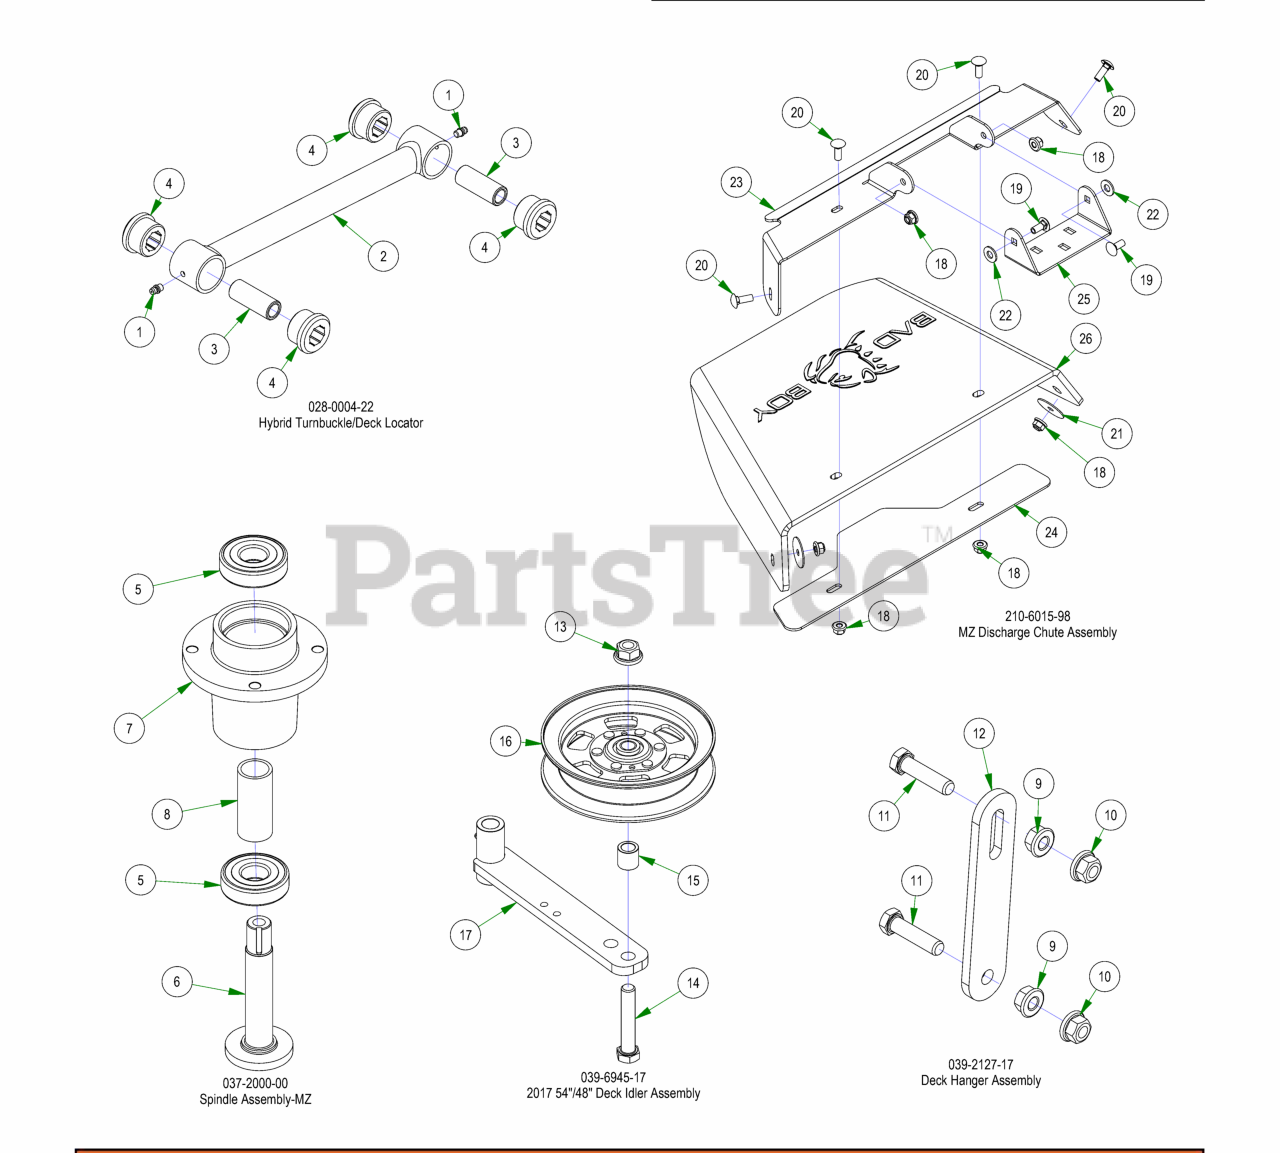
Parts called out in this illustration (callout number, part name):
1	1/4-28 Grease Fitting
2	2022 Isolator Turnbuckle Body
3	2018 Maverick Bushing Sleeve
4	2018 Maverick Bushing
5	Spindle Bearing
6	Spindle Shaft
7	Spindle Housing
8	Spindle Spacer-Component
9	3/8-16 HEX SERRATED FLANGE NUT HARD/ZINC
10	3/8-16 NYLON INSERT FLANGE LOCKNUT (GR.F) ZINC
11	3/8-16 X 1-1/2 HEX CAP SCREW (GR.5) ZINC
12	2017 MZ/ZT Deck Hanger
13	1/2-13 NYLON INSERT FLANGE LOCKNUT ZINC
14	1/2-13 X 2-3/4 HEX CAP SCREW (GR.5) ZINC
15	Spacer 3/4 OD x 1/2 ID x 3\4 Length
16	5" Idler Pully
17	Deck Idler
18	5/16" Nylon Flange Nut
19	5/16-18 x 3/4 Carriage Bolt
20	5/16-18 X 7/8 CARRIAGE BOLT ZINC
21	5/16 Fender Washer
22	.360 ID Plastic Washer
23	Discharge Chute Bracket 48 MZ (Upper)
24	2017 MZ Discharge Chute Bracket-Lower
25	Chute Hanger 48 MZ
26	Rubber Discharge Chute MZ (Component)
